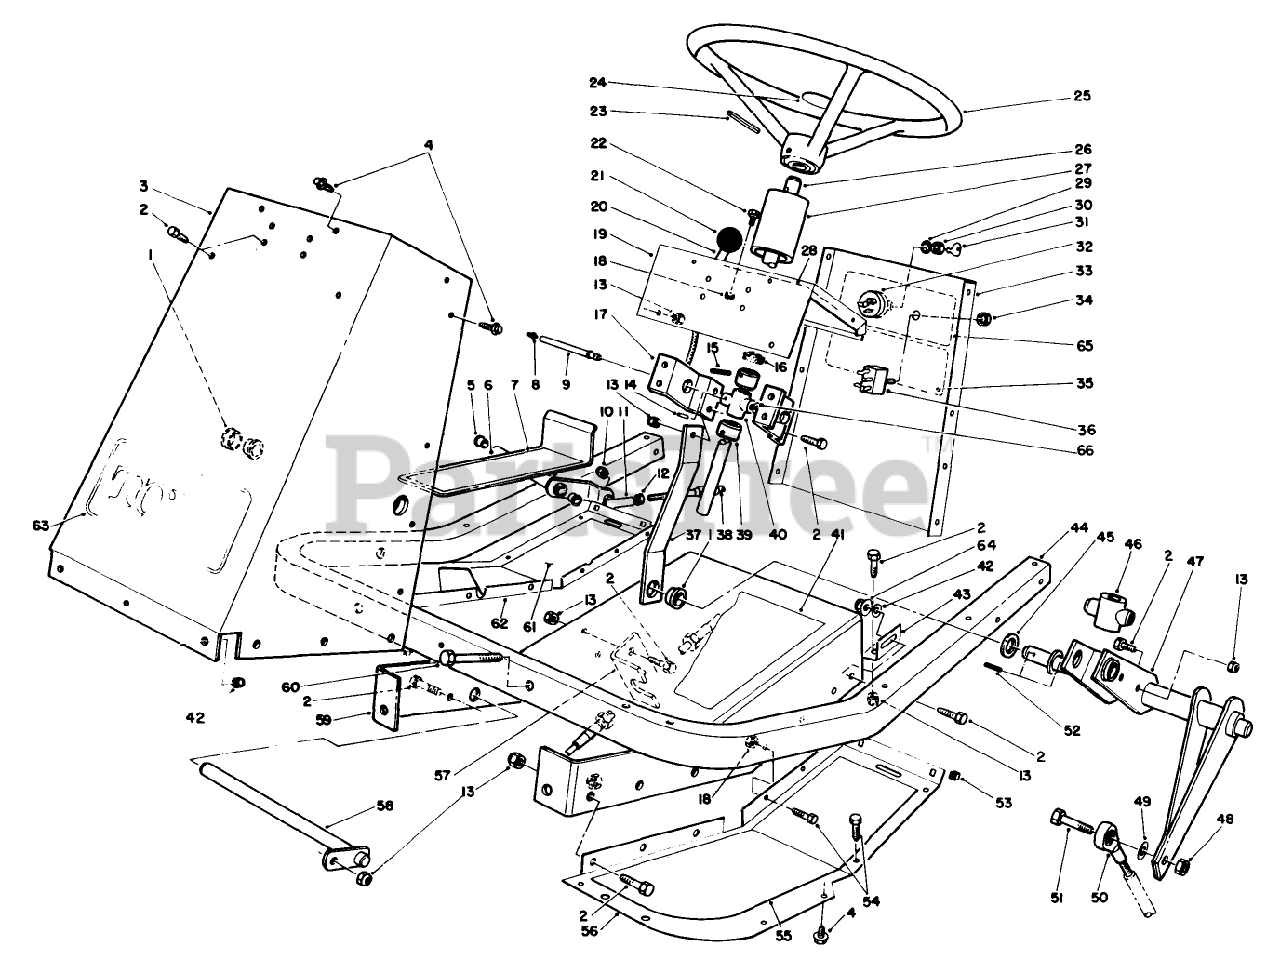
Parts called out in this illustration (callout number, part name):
1	BEARING-FLANGE
2	SCREW-HH
3	Tower-Front
4	SCREW-HHFTF
5	BUSHING-FLANGE
6	Traction Pedal (Incl. Ref. #5)
8	FITTING-GREASE
9	TUBE ZERK
10	NUT-LOCK
11	JOINT-BALL
12	NUT-JAM
13	NUT-LOCK, NI
14	3/32 X 9/16 ROLL PIN
15	PIN-SPRING
16	COVER-DUST
17	BRG SUPT BRKT
18	NUT-LOCK, NI
19	Tower-Top
20	CONTROL-CHOKE,THROTTLE
22	SCREW-HH
23	PIN-ROLL
24	STEERING WHEEL CAP
25	WHEEL-STEERING
26	STEERING SHAFT
27	STRG. SHAFT COVER
28	THROTTLE DECAL
29	Washer-Lock
30	Nut-Hex
31	KEY-IGNITION
32	Switch-Ignition (Incl. Ref. #29-31)
33	REAR TOWER PANEL R
34	NUT
35	SWITCH DECAL
36	Switch
37	Link-Steering
38	TRACT CONT.CABLE
39	STRG SHAFT COLLAR
40	BRG STEERING SHAFT
41	TUNNEL DECAL
42	WASHER-PLAIN
43	TUNNEL BRKT
44	Frame-Footrest
45	WASHER-THRUST
46	STEER.SHAFT FOLLOWER
47	Follower Lever
48	NUT-HEX
49	WASHER-FLAT
50	BALL JOINT LH
51	SCREW-HH
52	PIN-ROLL
53	NUT-RETAINED
54	SCREW-HH
55	FOOT REST PAD LH
56	Footrest-L.H.
57	TRACT CABLE BRKT
58	PEDAL.SHAFT WA
59	Tunnel
60	SCREW-HH
61	FOOT REST PAD RH
62	Footrest-R.H.
63	DECAL
64	NUT-HF
65	THROTTLE DECAL
66	WASHER-BELLEVILLE
